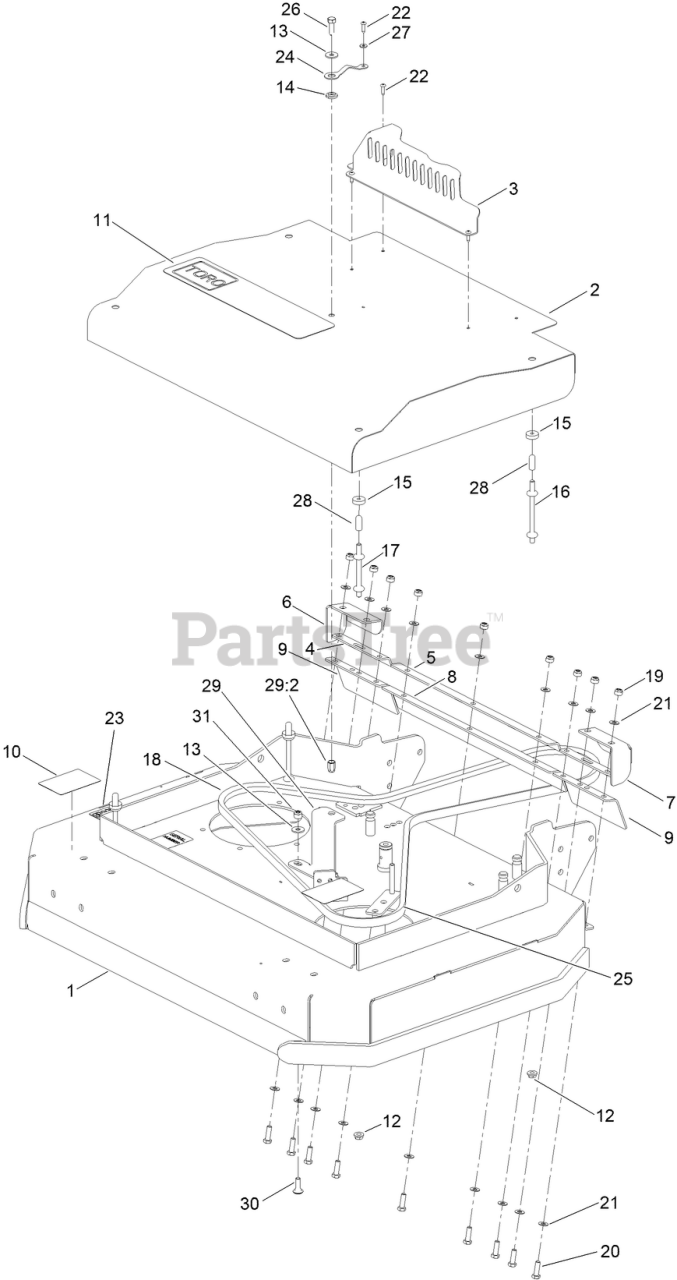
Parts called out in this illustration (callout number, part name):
1	36 INCH DECK ASM
2	COVER-DECK
3	GUARD-PIPE, EXHAUST
4	BRACKET-DEFLECTOR, SIDE
5	BRACKET-DEFLECTOR, CENTER
6	GUARD-DISCHARGE, RH
7	GUARD-DISCHARGE, LH
8	DEFLECTOR-CENTRE, RUBBER
9	DEFLECTOR-SIDE, RUBBER
10	DECAL-DANGER, CE
11	DECAL-TORO
12	NUT-HF
13	WASHER
14	NUT-RETAINER
15	WASHER
16	STUD-SHIELD, BELT (LONG)
17	STUD-SHIELD, BELT (SHORT)
18	BELT-V
19	NUT-NYLOC
20	SCREW-HH
21	WASHER
22	RIVET
23	DECAL-NOISE
24	LANYARD-3 INCH
25	GUIDE-BELT
26	SCREW-HH
27	WASHER
28	CAP-END, RUBBER
29	BRACKET-GUARD
29:2	NUT-RIVET
30	BOLT-COACH
